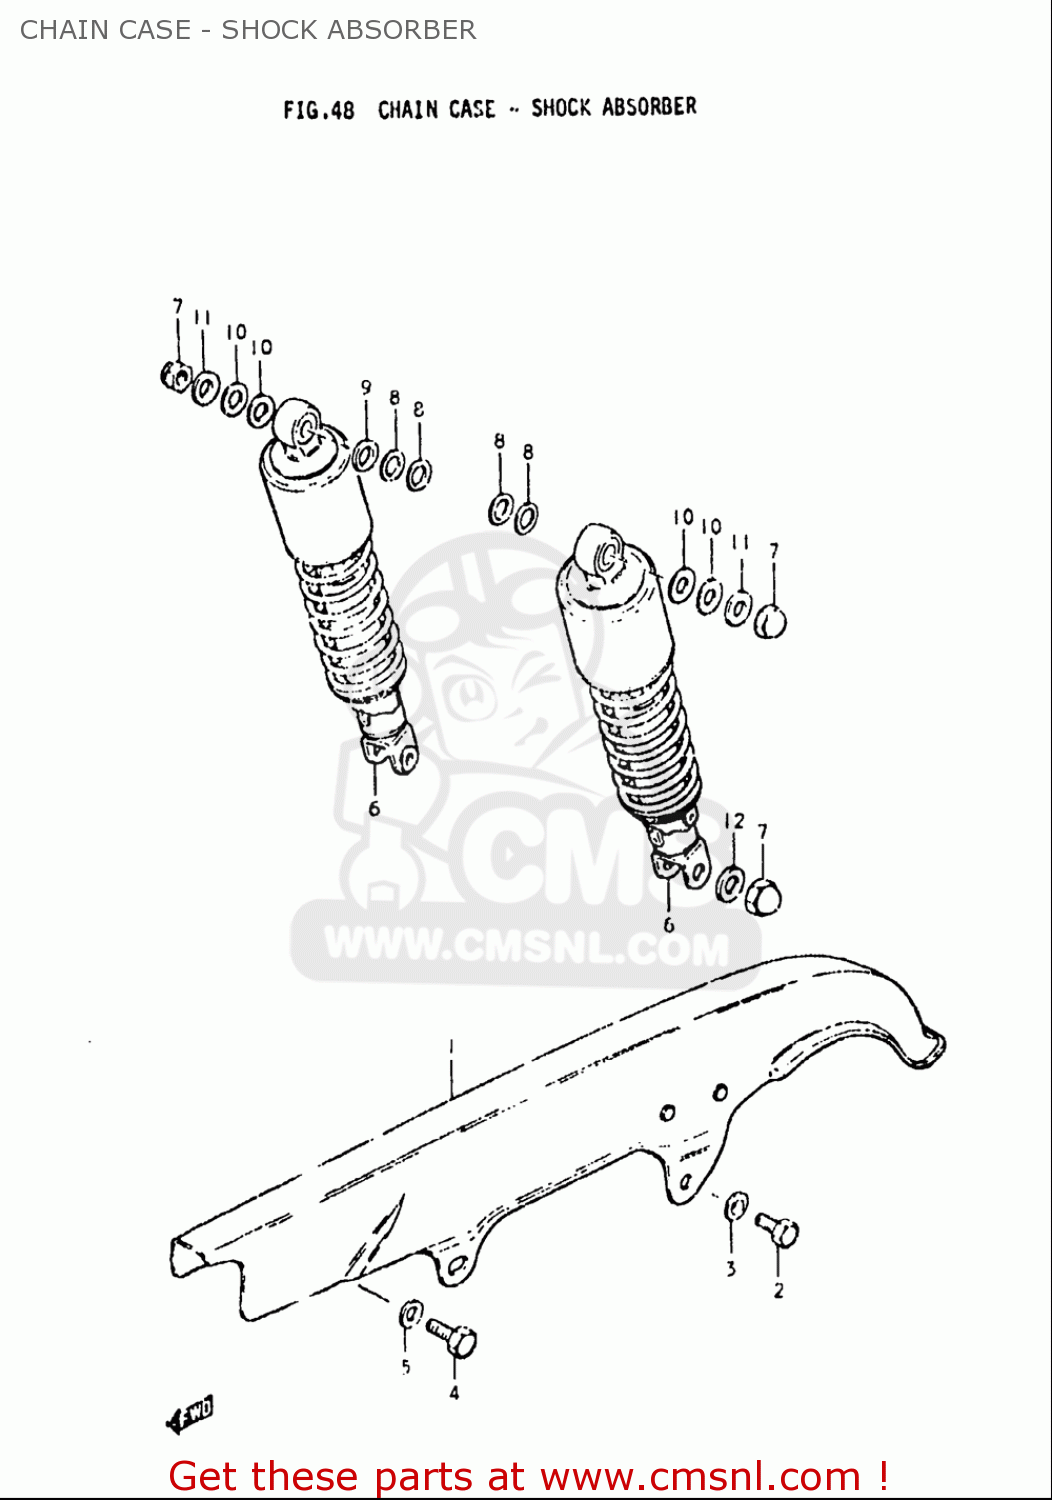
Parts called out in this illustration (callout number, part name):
1	CASE,CHAIN
2	BOLT(6X8)
3	WASHER
4	BOLT
5	WASHER(6.5X22X1.6)
7	NUT
8	WASHER
9	WASHER(12.5X24X3.2)
10	WASHER (10.5X24X2.3)
11	WASHER (10.5X25X3.2)
12	WASHER (10.5X24X2.3)
